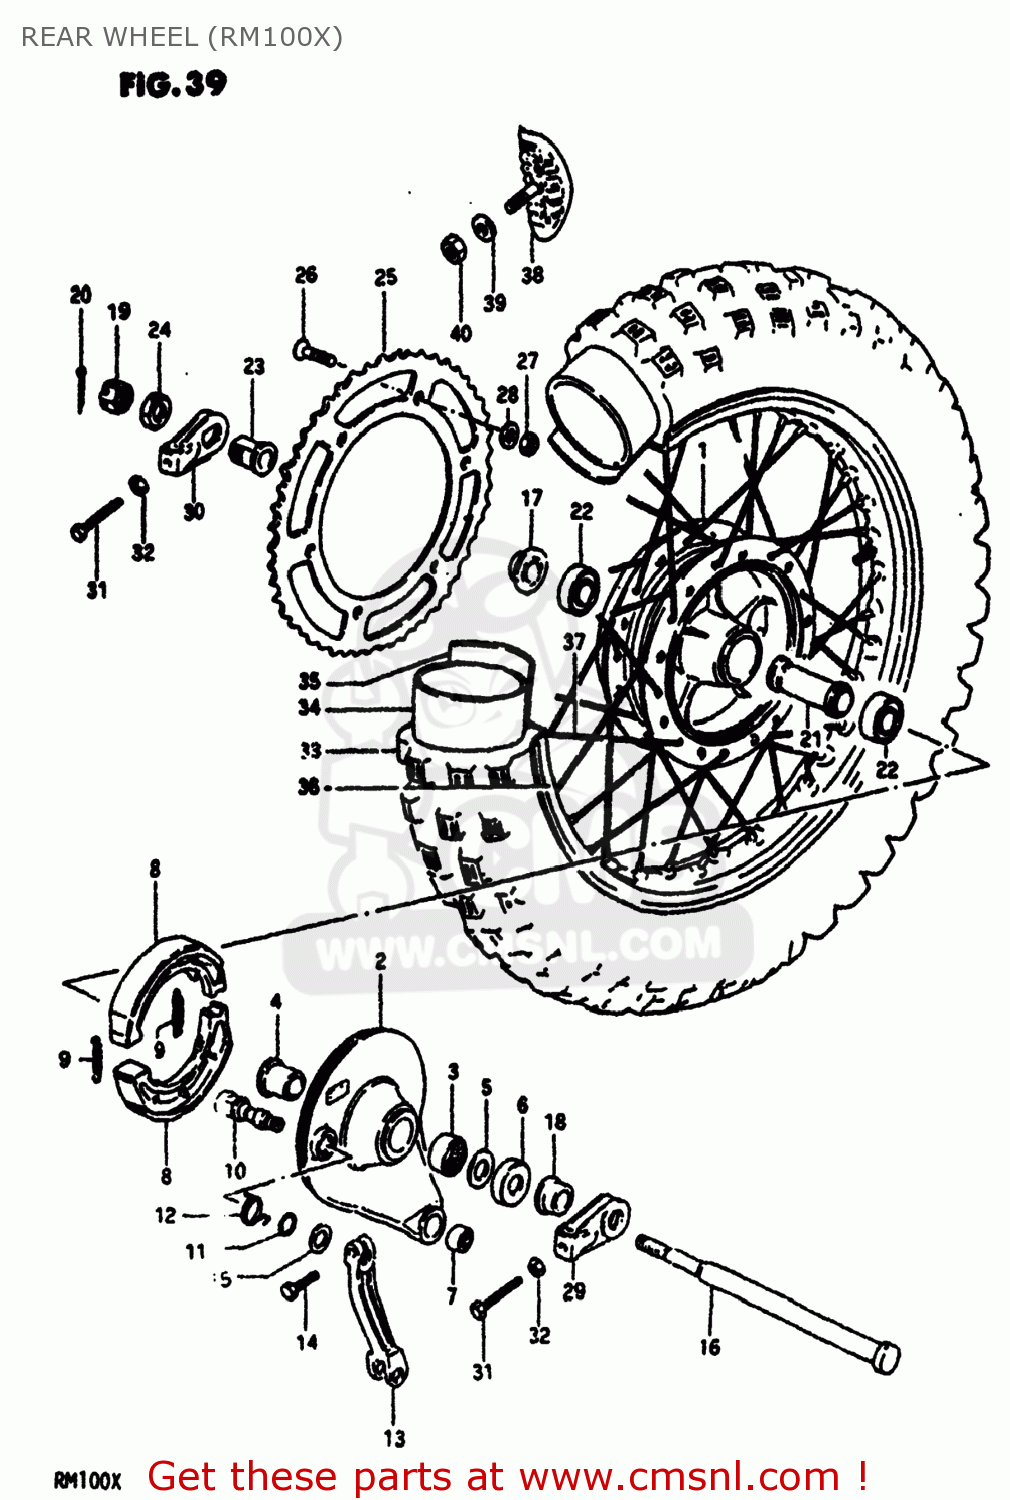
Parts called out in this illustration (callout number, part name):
1	DRUM,REAR HUB
2	PANEL SET,REAR HUB
3	BEARING(22X29X25)
4	SPACER,REAR HUB PANEL
5	WASHER
6	COVER, PANEL DUST SEAL
7	SPHERICAL BEARING,TORQUE
8	SHOE,BRAKE
9	SPRING(L:34)
10	CAM,FR BRAKE
11	O RING(D:2.5,ID:11.4)
12	SPRING
13	LEVER,RR BRAKE CAM
14	BOLT
15	WASHER(12.5X20X1)
16	AXLE,REAR
17	SPACER,RR AXLE,L
18	SPACER (15.2X26X34)
19	NUT 12MM
20	COTTER PIN
21	SPACER,REAR HUB BEARING
22	BEARING
23	SPACER,CHAIN ADJUSTER,L
24	NUT
25	SPROCKET,REAR
26	SCREW(8X33.5)
27	NUT
28	WASHER
29	ADJUSTER,CHAIN,R
30	ADJUSTER,CHAIN,L
31	BOLT(8X40)
32	NUT
33	TIRE
34	TUBE ASSEMBLY,WHEEL,INNER
35	PROTECTOR,INNER TUBE
36	RIM,REAR WHEEL
37	SPOKE SET,REAR WHEEL
38	STOPPER,BEAD
39	WASHER
40	NUT
